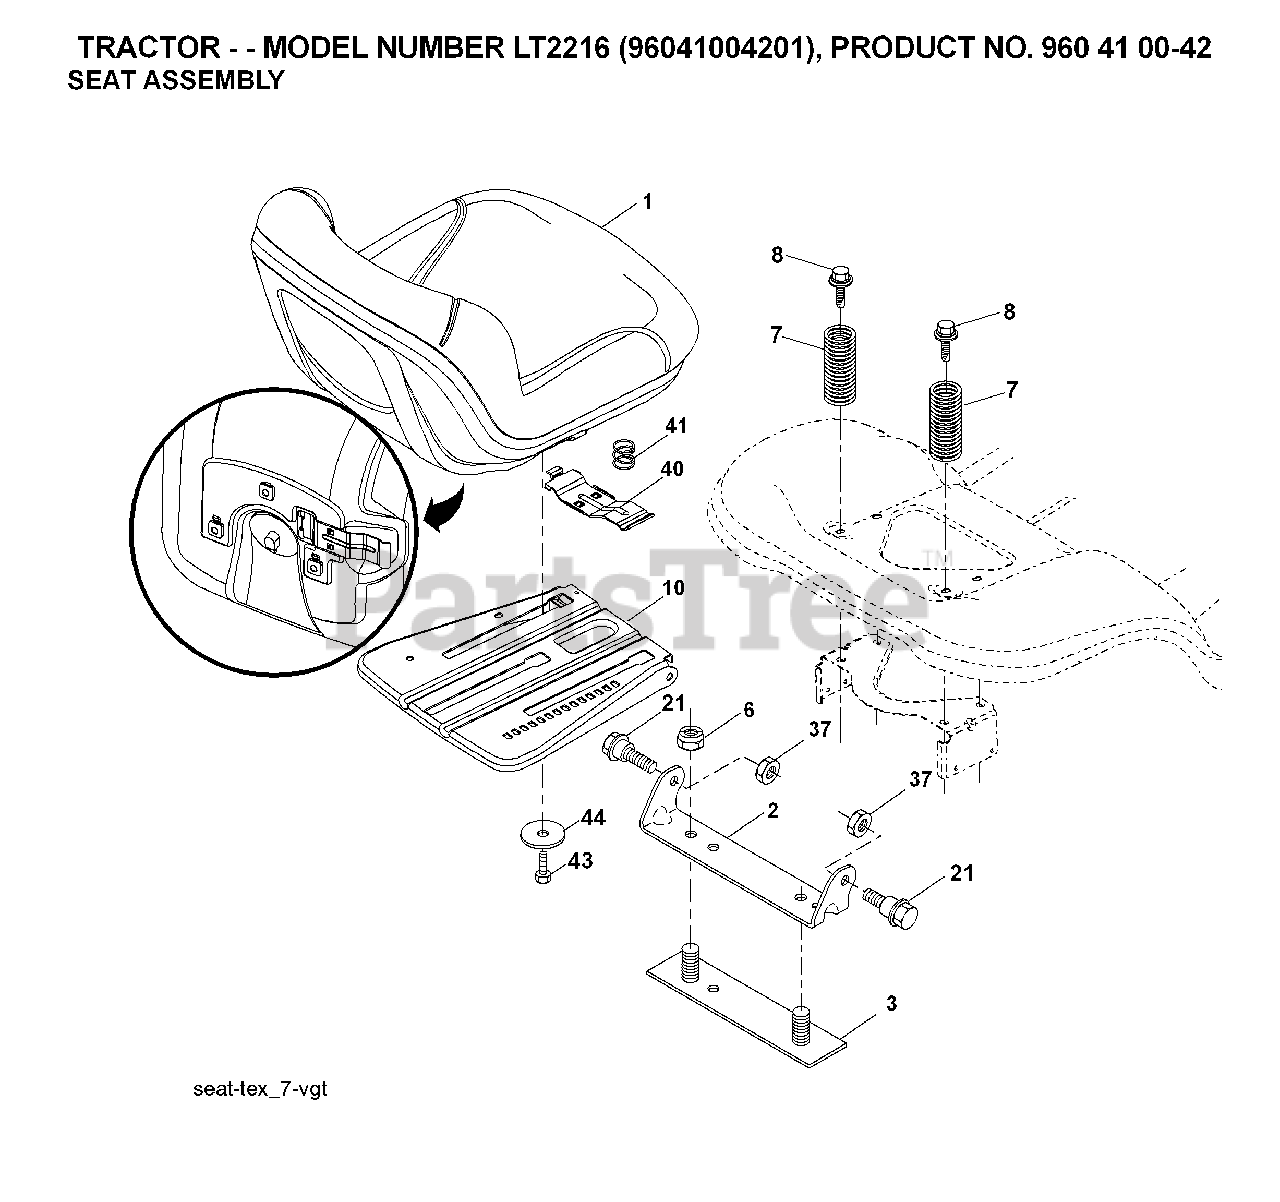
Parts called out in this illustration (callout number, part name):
1	SEAT.TG130.BLACK.NO/LOGO.
2	BRKT.PIVOT.FENDER
5	PUSH CLIP
6	NUT
7	SPRING COMPRESSION
8	BOLT, 5/16-18 X 1 3/4
10	PAN.ASM.SEAT.3PT
21	BOLT.SHOULDER.5/16-18
37	NUT.71038.31-18.HEX.NYLOCK
40	HANDLE.SLIDE.SEAT.TEX.BLACK
41	SPRING.LATCH.SEAT.TEX
44	WASHER 13/32 X 2-3/8 X 12GA
